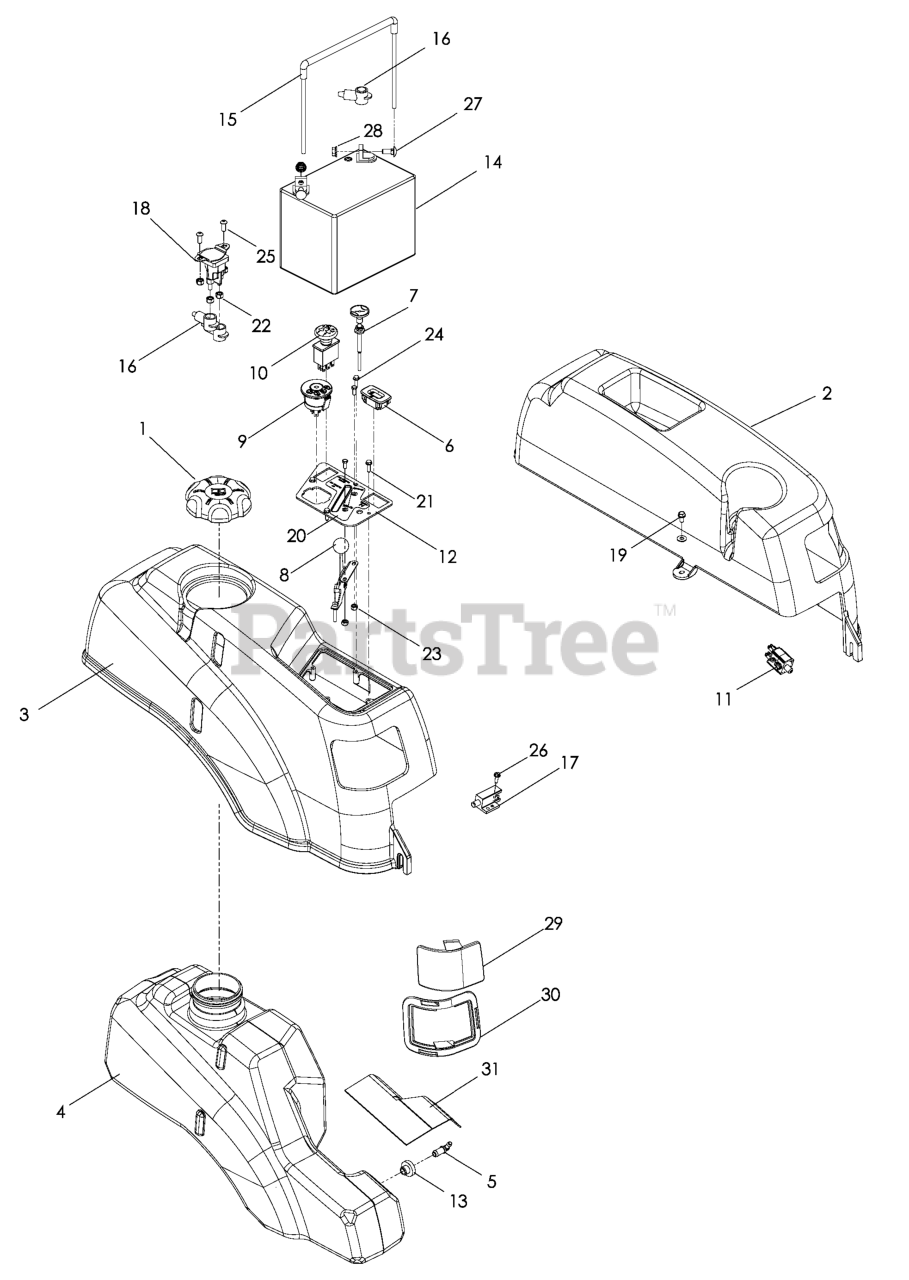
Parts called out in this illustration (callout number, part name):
1	FUEL CAP, HTC
2	FENDER, LT
3	RP.FENDER, RT
4	TANK, FUEL
5	STEM, FUEL TANK
6	HOUR METER
7	CHOKE CONTROL
8	THROTTLE CABLE
9	RP IGNITION SWITCH
10	RP.SWITCH, BLADE
11	SWITCH, BRAKE 3P
12	CONSOLE.PLATE.BLACK
13	RUBBER GROMMET
14	BATTERY, 12 V 330 AMP
15	BATTERY TIE DOWN ASSEMBLY
16	TERMINAL COVER-SM
17	SWITCH, INTERLOCK
19	BOLT 1/4-20 X 1/2 HWST
20	DECAL, IGNITION CONSOLE
21	HCS #10-24 X 1/2
22	NUT.1/4-20.HEX.NYLOC.ZD
23	NUT 10-24 NYLOC
24	SCR #10-12X3/4 HEX WAS HD ZD
25	SCR 1/4-20 X 5/8 BTN SKT HD ZD
26	SCREW #10 X 1/2 SELF TAPPING
27	BOLT 5/16C X 3/4" CARRIAGE
28	NUT 5/16C WHIZ
29	LENS, COLORED LEFT
30	LENS, COLORED RIGHT
31	LEFT HEADLIGHT RIM GREY
